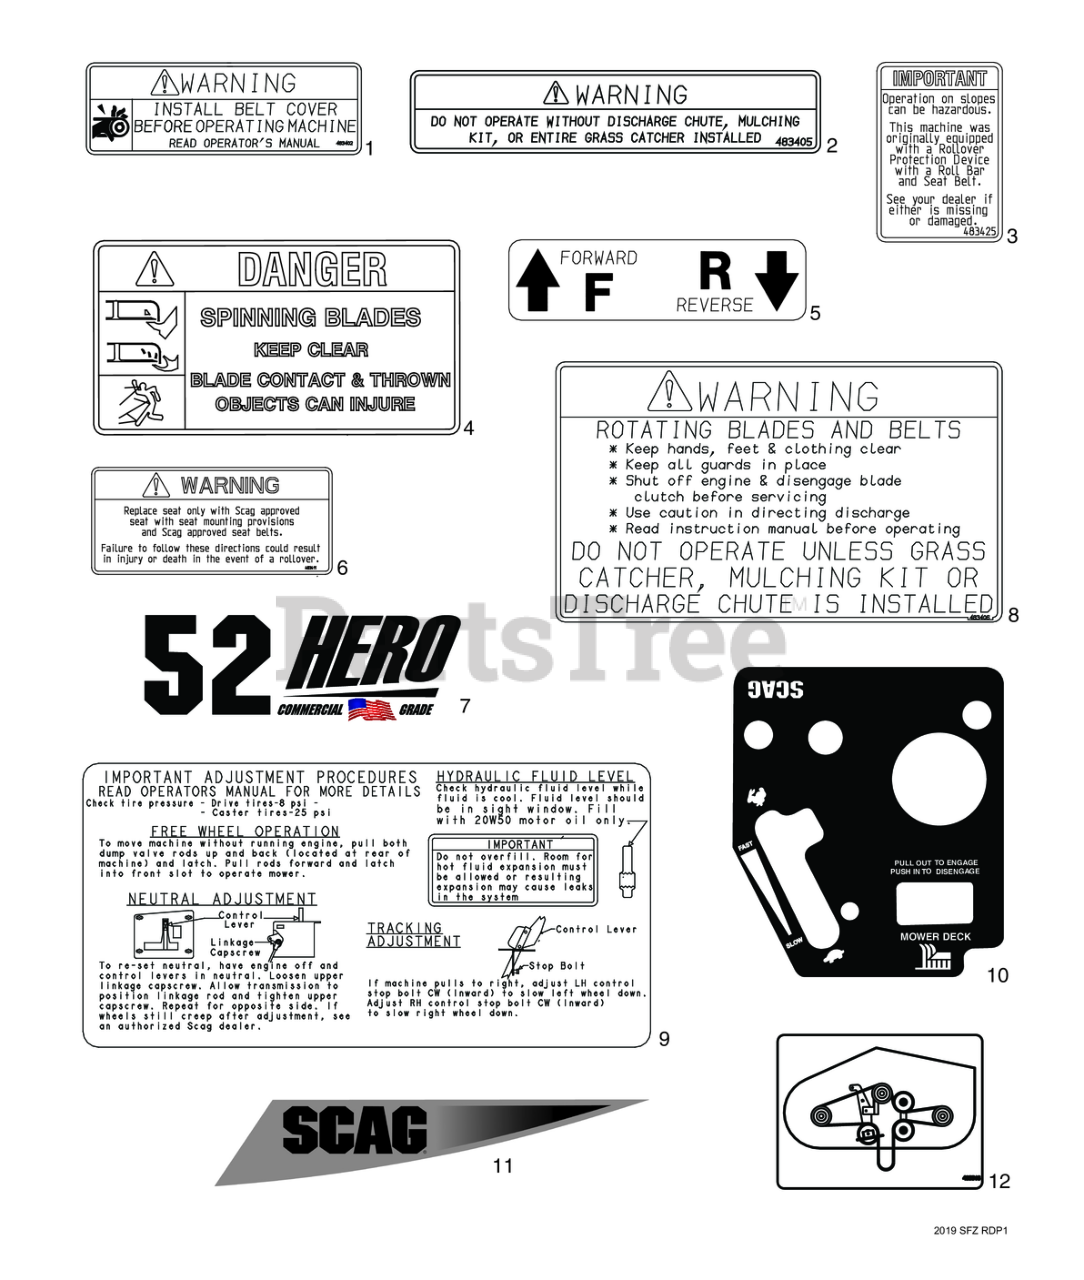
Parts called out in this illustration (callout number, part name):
1	Decal, Warning - Belt Cover
2	Decal, Warning-Discharge
3	Decal, ROPS
4	Decal, Spinning Blades
5	Decal, Traction Control
6	Decal, Seat Replacement
7	Decal, 52H Commercial
8	Decal, Warning - Rotating Blades
9	Decal, Adjustment SFZ
10	Decal, Instrument Panel - SFZ48, SFZ52 & SFZ 61
11	Decal, Scag RH Fuel Tank
11	Decal, Scag LH Fuel Tank
12	Decal, SZL / SFZ / SPZ Belt Routing
